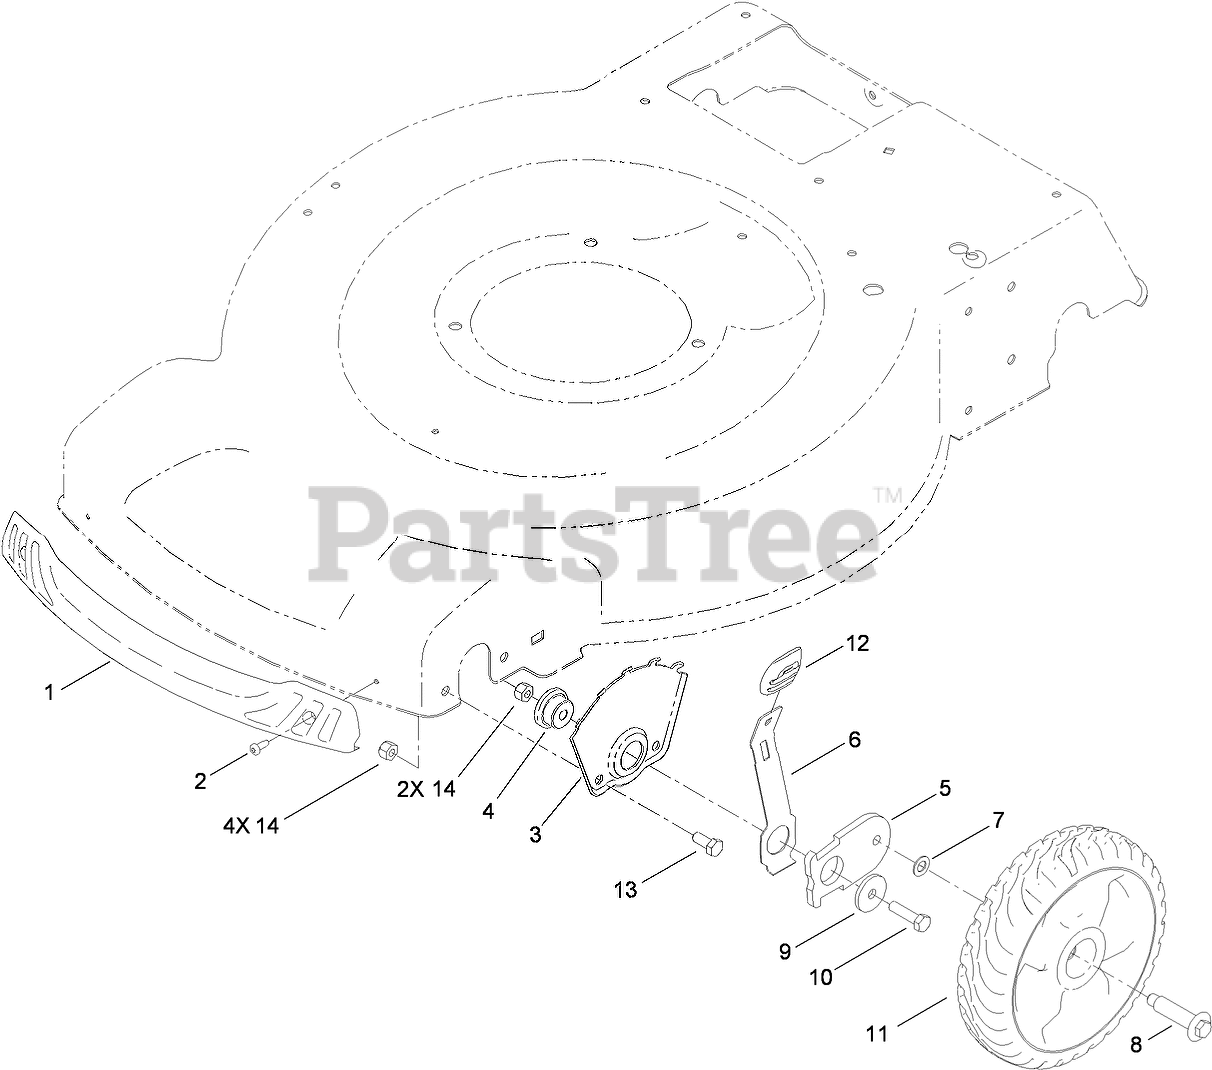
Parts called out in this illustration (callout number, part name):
1	BUMPER
2	SCREW-FORMING, THREAD
3	PLATE-HOC, FRONT
4	Bushing-Mount, HOC
5	ARM-PIVOT, FRONT
6	Arm-Spring
7	WASHER
8	BOLT-SHOULDER
9	Washer-Flat
10	SCREW-HH
11	8 INCH WHEEL ASM
12	Knob-Lever, HOC
13	SCREW-HH
14	NUT-LOCK, NI
